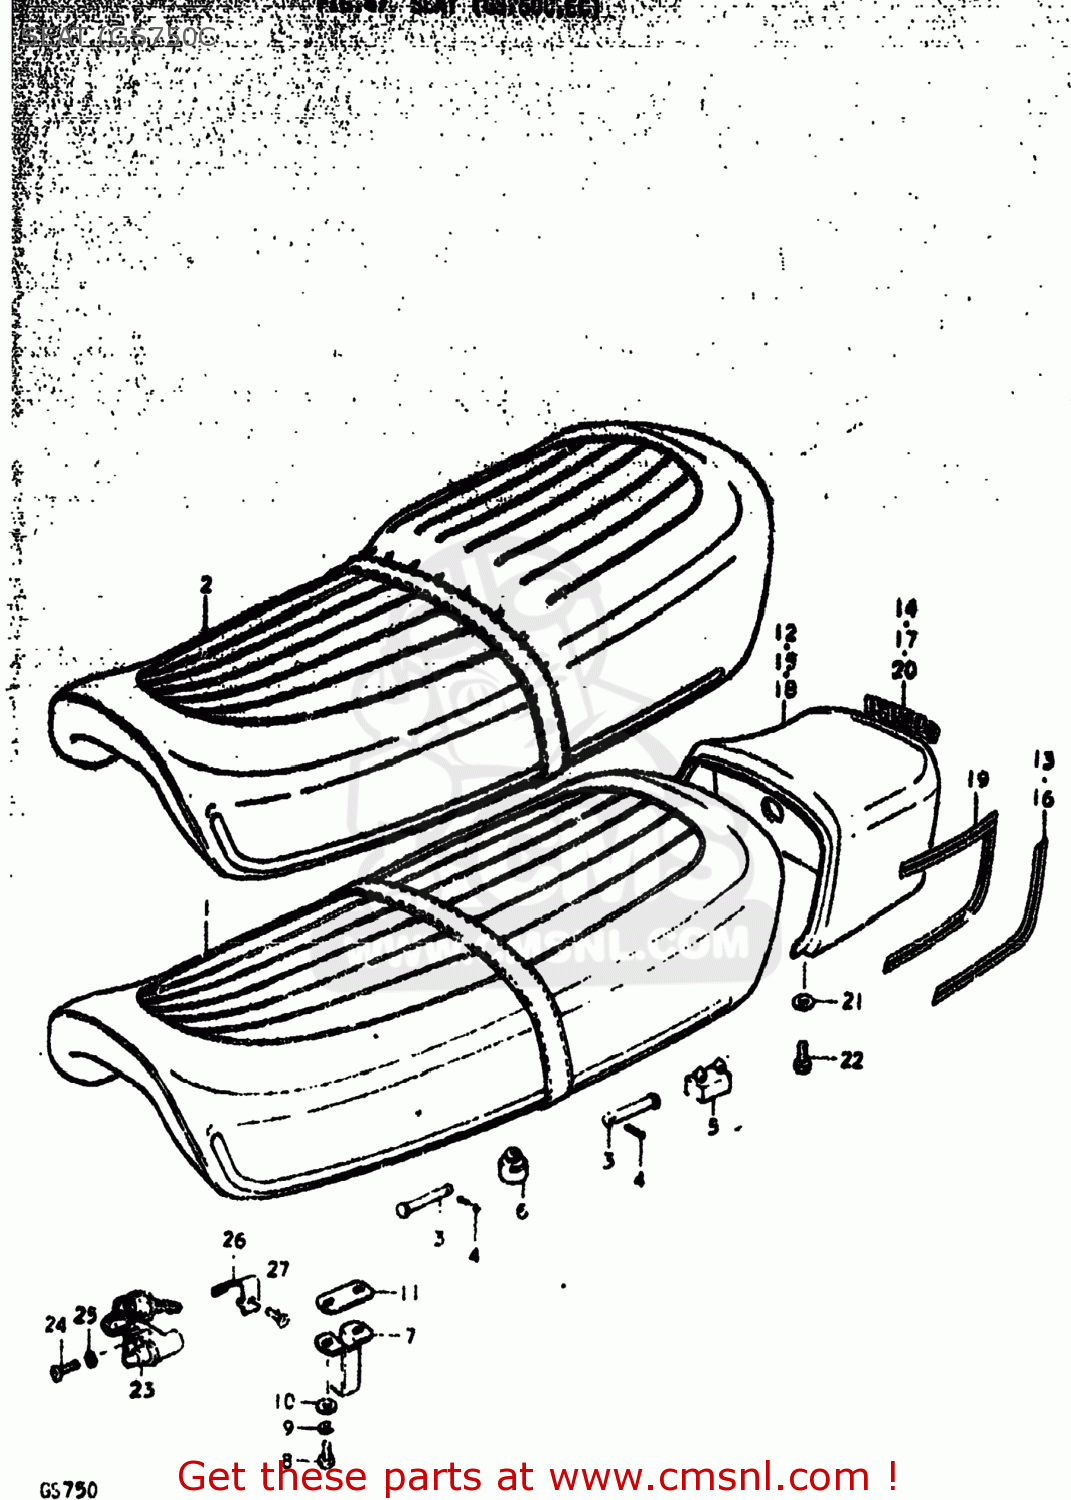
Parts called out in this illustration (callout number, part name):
1	SEAT ASSEMBLY
2	SEAT ASSEMBLY
3	PIN
4	PIN
5	CUSHION
6	CUSHION
7	STRIKER,SEAT LOCK
8	BOLT
9	LOCK WASHER
10	WASHER
11	SHIM,SEAT LOCK STRIKER
12	COVER,SEAT TAIL
14	EMBLEM
15	COVER,SEAT TAIL
16	TAPE, SET
17	EMBLEM
18	COVER,SEAT TAIL
20	EMBLEM
21	WASHER
22	BOLT, UPPER
23	LOCK ASSEMBLY,SEAT
24	SCREW
25	LOCK WASHER
26	SPRING,HELMET HOLDER
27	SCREW
